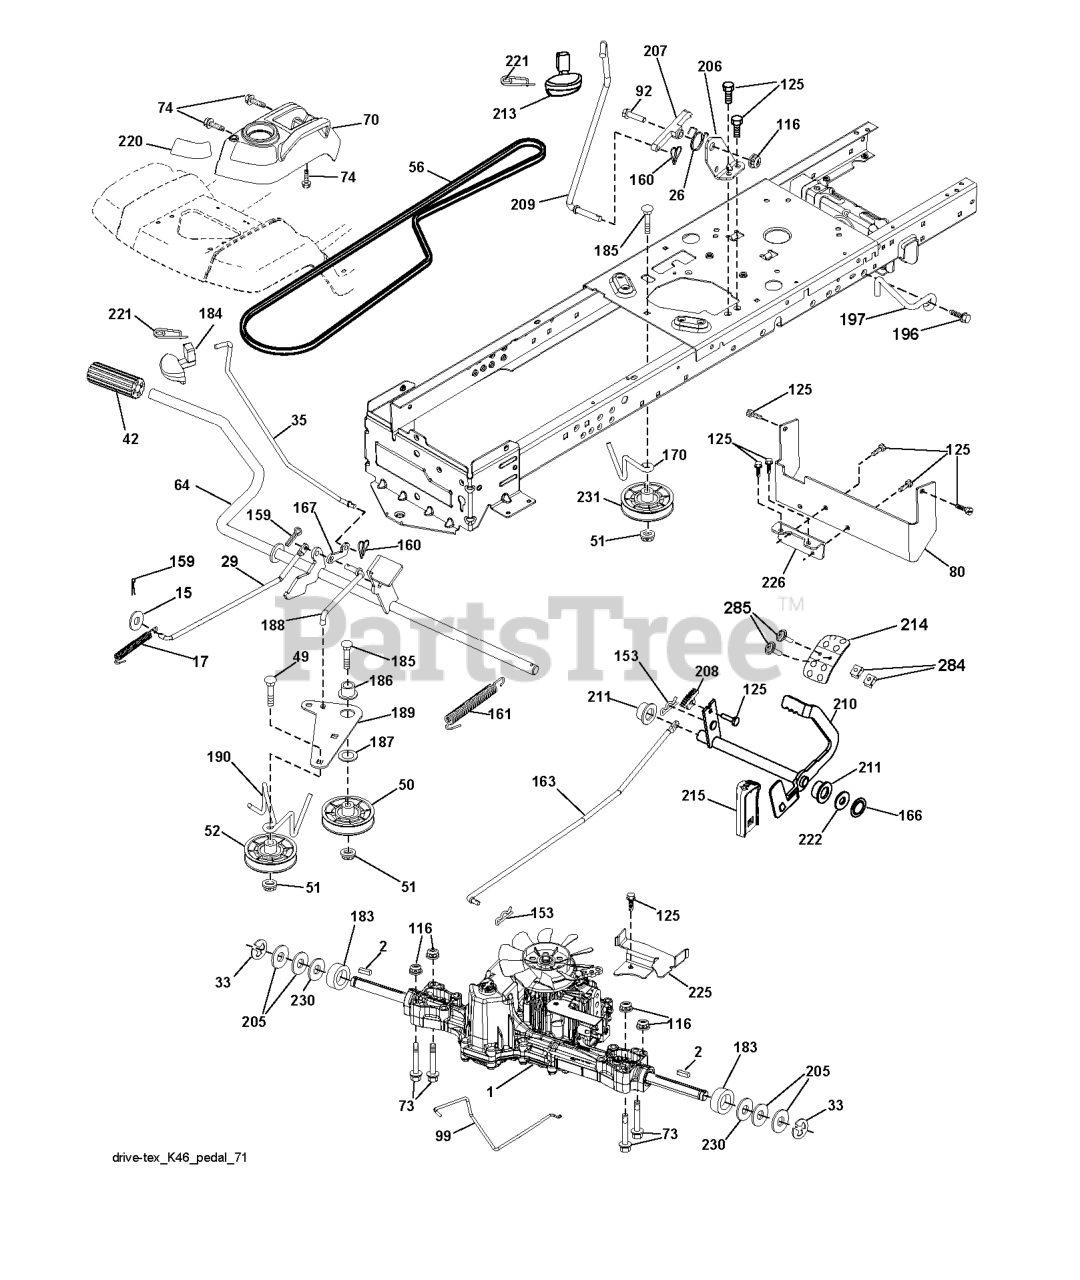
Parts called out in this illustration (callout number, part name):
2	SQUARE KEY
15	WASHER
17	SPRING.BRAKE.K46.GREEN
26	SPRING.RETURN.CRUISE
29	ROD.BRAKE.K46
35	ROD.BRAKE.PARKING.GT.H
42	PEDAL COVER T
50	IDLER.FLAT.910.OFFSET
51	NUT LOCK FLG 3/8-16 UNC
52	IDLER.V-GROOVE.910.OFFSET
56	V-BELT.MOWER.92.40.42/K46
64	SHAFT.ASM.PEDAL.BRK.CNTR
70	RP CONSOLE.ASM.PCH.W/TB
73	BOLT HEX 5/16-18 GR 5
74	SCREW.HI-LO.CONSOLE
80	STRAP TORQUE
92	BOLT
99	ROD.SPRING.BYPASS.K46.LT.Z
116	NUT LOCK HEX FLANGE 5/16-18
125	SCREW
153	RETAINER M
159	COTTER PIN
160	RETAINER CLIP
161	SPRING, RETURN LT
163	ROD.CONTROL.PEDAL.K46
166	NUT.PUSH.625
167	LATCH.BRAKE.SPRING
170	KEEPER.CENTER SPAN.1.688
183	SPACER AXLE
184	HANDLE.PARKG.BRK.HUSQ X667
186	SPACER.RETAINER
187	WASHER 12/32X2X10GA
188	RP.LINK.CLUTCH.GROUND.DRIVE
189	BELLCRANK.GROUND.DRIVE.TEX.
190	KEEPER.BELLCRANK.DRIVE
196	SCREW 3/8-16X1
197	LINK.CLUTCH.ANIT-ROTAT
206	BRKT.MOUNT.LATCH.CRUIS
207	LATCH.CONTROL.CRUISE
208	GEAR.SECTOR.CONTROL.CR
209	ROD.CONTROL.CRUISE.GT.
210	ROCKER.ASM.PEDAL.CONTR
211	BEARING.NYLON
213	KNOB.CONTROL.CRUSIE.HU
214	PEDAL.FORWARD.HUSQVARNA.DEALER
215	PEDAL.REVERSE.TEX.GT.4
220	REFLECTOR.RH.TEX GT
221	RETAINER.SPRING.CLIP.H
222	WASHER 21/32 X 1-1/4 X 10 GA.
225	KEEPER.BELT.TRANSAXLE.K46
226	BRACKET.MOUNT.TORQUE.K46.TLT
230	WASHER.HARDENED
231	IDLER.V-GROOVE.1.688.OFFSET
284	NUT.U-CHNL.1/4-20.550DP.350PNL
285	SCREW.PHD.1/4-20.BOX DRVE
